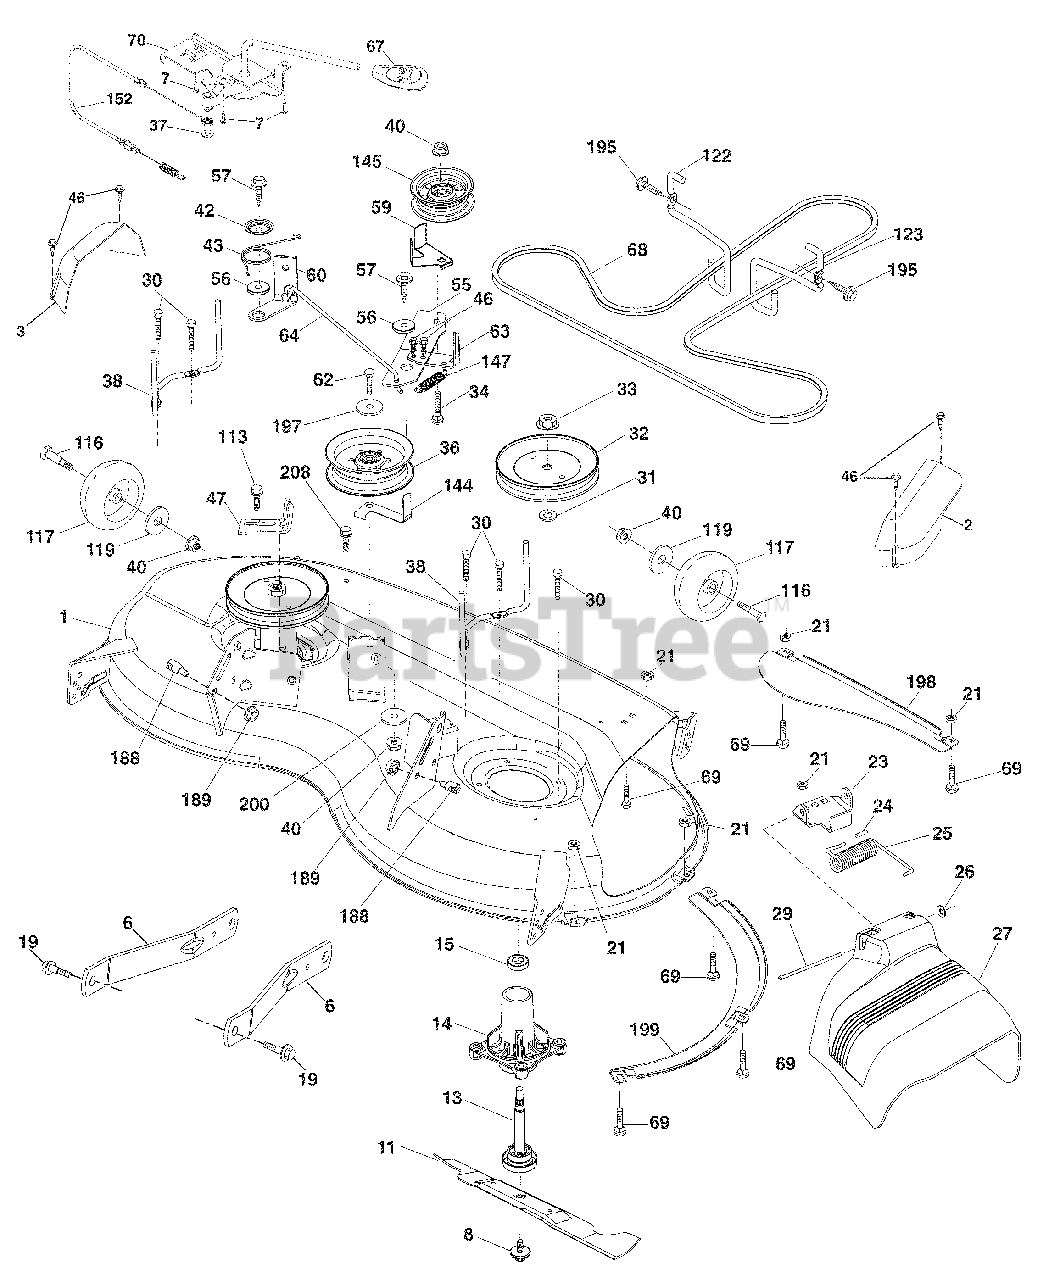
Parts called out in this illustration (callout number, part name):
1	Mower Housing
2	Cover Mandrel RH
3	Cover Mandrel LH
6	Arm Suspension
7	Screw # 10 x 0.750
8	Bolt/Washer asm 7/16-20 unf
11	Blade Mower Hi Lift
13	Shaft Assembly, Mandrel
14	Housing, Mandrel
15	Bearing, Ball, Mandrel
19	Bolt, Shoulder
21	Nut
23	Bracket, Deflector
24	Cap, Sleeve
25	Spring, Torsion, Deflector
27	Shield, Deflector
29	Rod, Hinge
30	Screw Thdrol Rolling Wsh Hd
31	Washer, Spacer
32	Pulley, Mandrel
33	Nut, Toplock, Flanged
34	Bolt Carr Sh. 3/8-16 x 1-1/2 Gr. 5
36	Pulley, Idler, Flat
37	Washer 13/32 x 13/16 x 16 Ga.
38	Keeper Belt LH Mandrel
40	Nut, Lock Flg. 3/8-16 unc
42	Spring Torsion Brake
43	Spring Torsion Retainer
47	Bracket Clutch Cable
55	Arm, Idler
56	Spacer, Retainer
57	Screw Hexwsh Thd 3/8-16 x 1
59	Guard, Tuv Idler (94)
60	Arm Brake Mower LH
62	Bolt 3/8-16 UNC x 2-1/4 Gr. 5
63	Arm Brake Mower
64	Linkage Brake
67	Handle, Clutch Cable
68	V-Belt
69	Bolt
70	Clutch Asm. Cable
113	Screw 5/16-18
116	Bolt, Shoulder
117	Wheel, Gauge
119	Washer 13/32 x 1-1/4 x 12 Ga.
122	Keeper Belt Eng. LH
123	Keeper Belt Eng. RH
144	Keeper Belt
145	Pulley Idler
147	Spring Return
152	Cable Clutch Manual w/Spr.
188	Stud Fastener
189	Nut Lock Hex Flange
195	Screw 3/8-16 x 3/4
197	Washer 13/32 x 13/16 x 12 Ga.
198	Baffle Center Front
199	Baffle Front RH
200	Washer 13/32 x 1 x 1/2 11 Ga.
208	Screw 3/8-16 x 1/2
